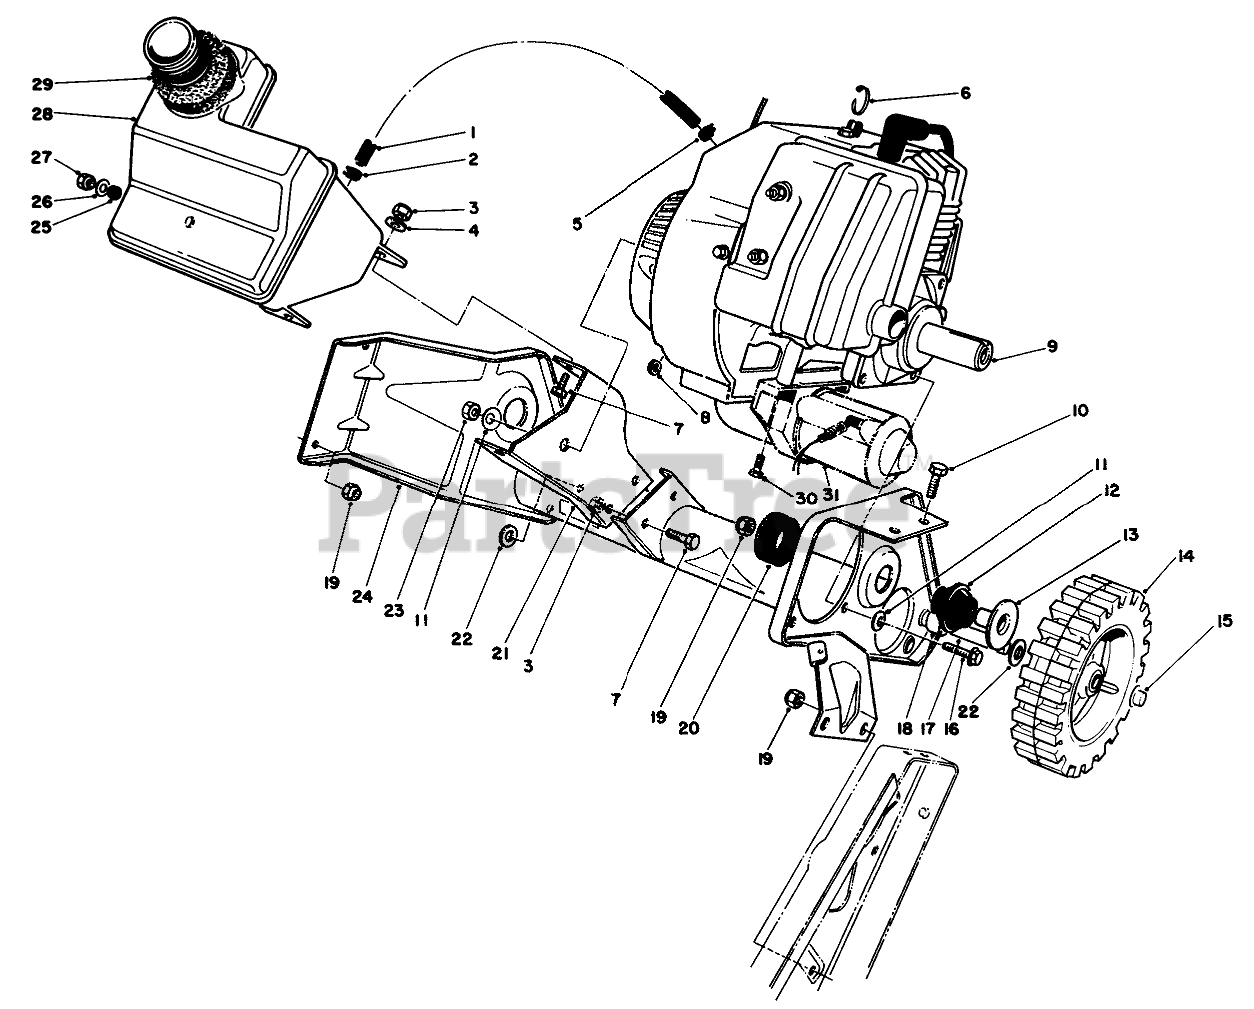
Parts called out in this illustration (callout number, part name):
1	GasLine
2	Clamp
3	NUT-LOCK, NI
4	WASHER-FLAT
5	CLAMP-HOSE
6	TIE-CABLE
7	SCREW-HH
8	SPACER-PLATE, PIVOT
9	Engine Assembly
10	SCREW-HH
11	WASHER-BELLEVILLE
12	MOUNT-REBOUND
13	SPACER TUBE
14	WHEEL
15	RETAINER-PUSH ON
18	WHEEL SPACER
19	NUT-LOCK, NI
20	LOAD MOUNT
21	Support-Recoil
22	WASHER-FLAT
23	NUT (F/W & PPP)
24	Frame Assembly
25	GROMMET-RUBBER
26	WASHER-PLAIN
27	NUT-LOCK, CONE
28	Tank-Fuel (Incl. Ref. #25)
29	SEAL-FOAM
30	SCREW
31	Starter Motor
